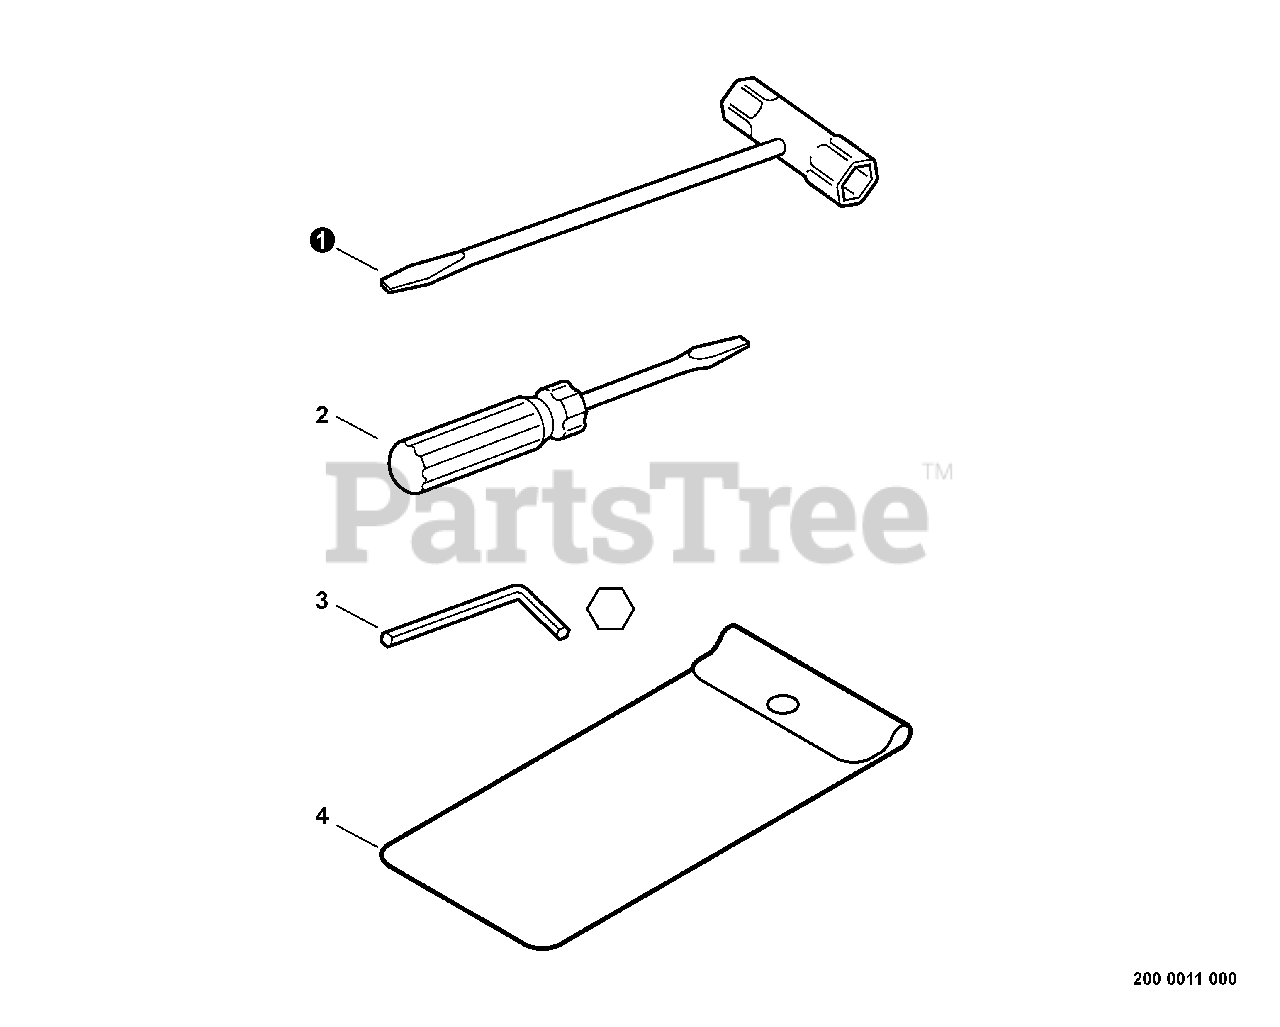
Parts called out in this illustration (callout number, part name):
1	T-WRENCH - 13X19mm
2	SCREWDRIVER
3	KEY - TORX -- T27
4	BAG, TOOL
